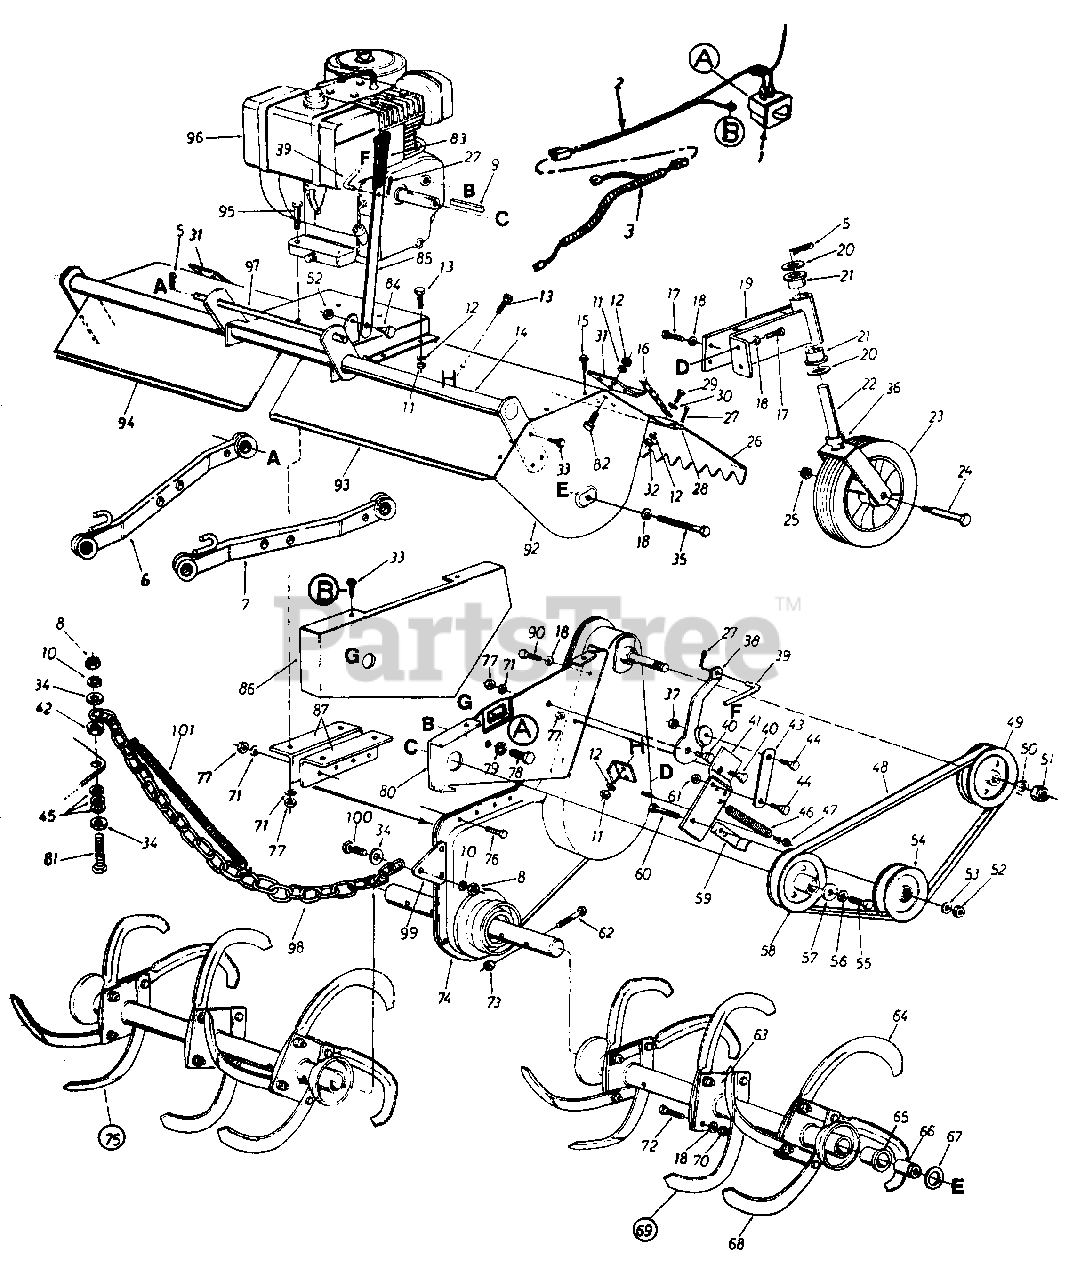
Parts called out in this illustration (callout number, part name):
1	Safety Switch
2	Wire Harness
3	Adapter Harness
5	Internal Cotter Pin
6	Draft Bar Ass'y.- R.H.
7	Draft Bar Ass'y.- L.H.
8	Hex Nut 3/8-24 Thd.
9	Sq. Key 1/4" x 1/4" x 2" Lg.
10	L-Wash. 3/8" I.D.
11	Hex Nut 1/4-28 Thd.
12	L-Wash. 1/4" I.D.
13	Hex Bolt 1/4-28 x .62" Lg.
16	#2 Dog Chain x 20" Lg.
17	Hex Wash. Hd. Self-Tap Scr. 3/8-24 x .75" Lg.
18	L-Wash. 3/8" I.D.
21	Flange Bearing 3/4" I.D. x 1.00" O.D.
24	Shoulder Bolt .623" I.D. x 3.62" Lg.
25	Hex Cent. L-Nut 7/16-14 Thd.
28	L.H. Flap Rod
29	Hex Bolt 1/4-20 x .62" Lg.
30	Fl-Wash. 1/4" I.D.
33	Hex Wash. Wd. Self-Tap Scr. 1/4" x .62" Lg.
34	Fl-Wash..385" I.D. x 1.0" O.D. x .135 Thk.
35	Hex Bolt 3/8-16 x 1.25" Lg.
36	Spacer .752" I.D. x 1.25" O.D.
37	Hex Cent. L-Nut 5/16-18 Thd.
40	Shoulder Bolt 7/16" Dia. x 1.75"
45	Fl-Wash. .406" I.D. x.74" O.D. x .063 Thk.
46	Extension Spring .62" O.D. x 6.12" Lg.
47	Hex Crown Nut 3/8-24 Thd.
48	"V"-Belt (Kevlar)
49	1/2" "V"-Pulley 4.75" O.D. x .625" Bore
50	L-Wash. 5/8" I.D.
51	Hex Ins. L-Nut 5/18-16 Thd.
52	Hex Cent. L-Nut 3/8-16 Thd.
53	Fl-Wash. 3/8" I.D.
54	Idler Pulley 4.0" O.D.
55	Hex Bolt 7/16-20 x 1" Lg.
56	L-Wash. 7/16" I.D.
57	Fl-Wash. 7/16" I.D. x 1.38"
58	1/2" "V"-Pulley .475" O.D. x 1.00" Bore
61	Hex Cent. L-Nut 5/16-18 Thd.
62	Hex Bolt 7/16-14 x 2.00" Lg.
66	Spacer
67	Thrust Wash. 1/2" I.D. x 1.55"
71	L-Wash. 5/16" I.D.
72	Hex Bolt 3/8-24 x 1.5" Lg.
73	Hex Cent. L-Nut 7/16-14 Thd.
77	Hex Nut 5/16-18 Thd.
78	Hex Bolt 1/2-20 x .88" Lg.
79	L-Wash. 1/2" I.D.
80	Clutch Support Bracket
81	Hex Bolt 3/8-24 x 1.75" Lg.
82	Hex Bolt 1/4-28 x .75" Lg.
83	Plastic Grip
84	Shoulder Bolt .498" Dia. x .212" Lg.
96	8 H.P. Engine
97	Tiller Mounting Shaft 16" Lg.
98	Chain 23" Lg.
99	Tiller Mounting Bracket
100	Hex Bolt 3/8-24 x 1.25" Lg.
101	Extension Spring
04975-0637	PLATE ASSY-SIDE-LH - POWDER BLACK (0637)
04978-0637	SUPPORT-SWIVEL WHE - POWDER BLACK (0637)
04983-0637	L.H.-Tine Shield - POWDER BLACK (0637)
14298-0637	SHROUD-CLUTCH SUP - POWDER BLACK (0637)
